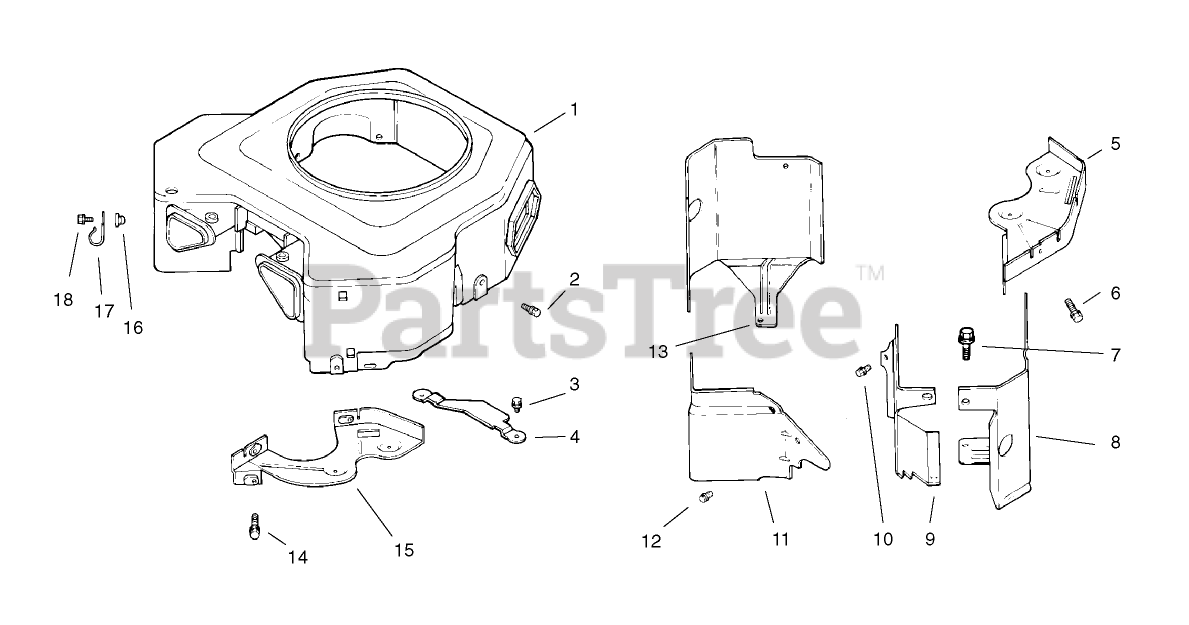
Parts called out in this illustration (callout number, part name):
1	Housing-Blower ASM (Only C)n: 72103, 72083)
2	Screw
3	Screw
4	Guard-Flywheel (Only On: 72103, 72083)
5	Plate-Backing #2 side
6	Screw
7	Screw
8	Baffle Cylinder #2 Side
9	Baffle-Valley #1 Side
10	Screw
11	Baffle-Valley #2 Side (Only On: 72103, 72083)
12	Screw
13	Baffle-Cyl. #1 Side
14	Screw
15	Plate-Backing #1
16	Nut
17	Clip-Cable (Only On: 72103)
18	Screw
